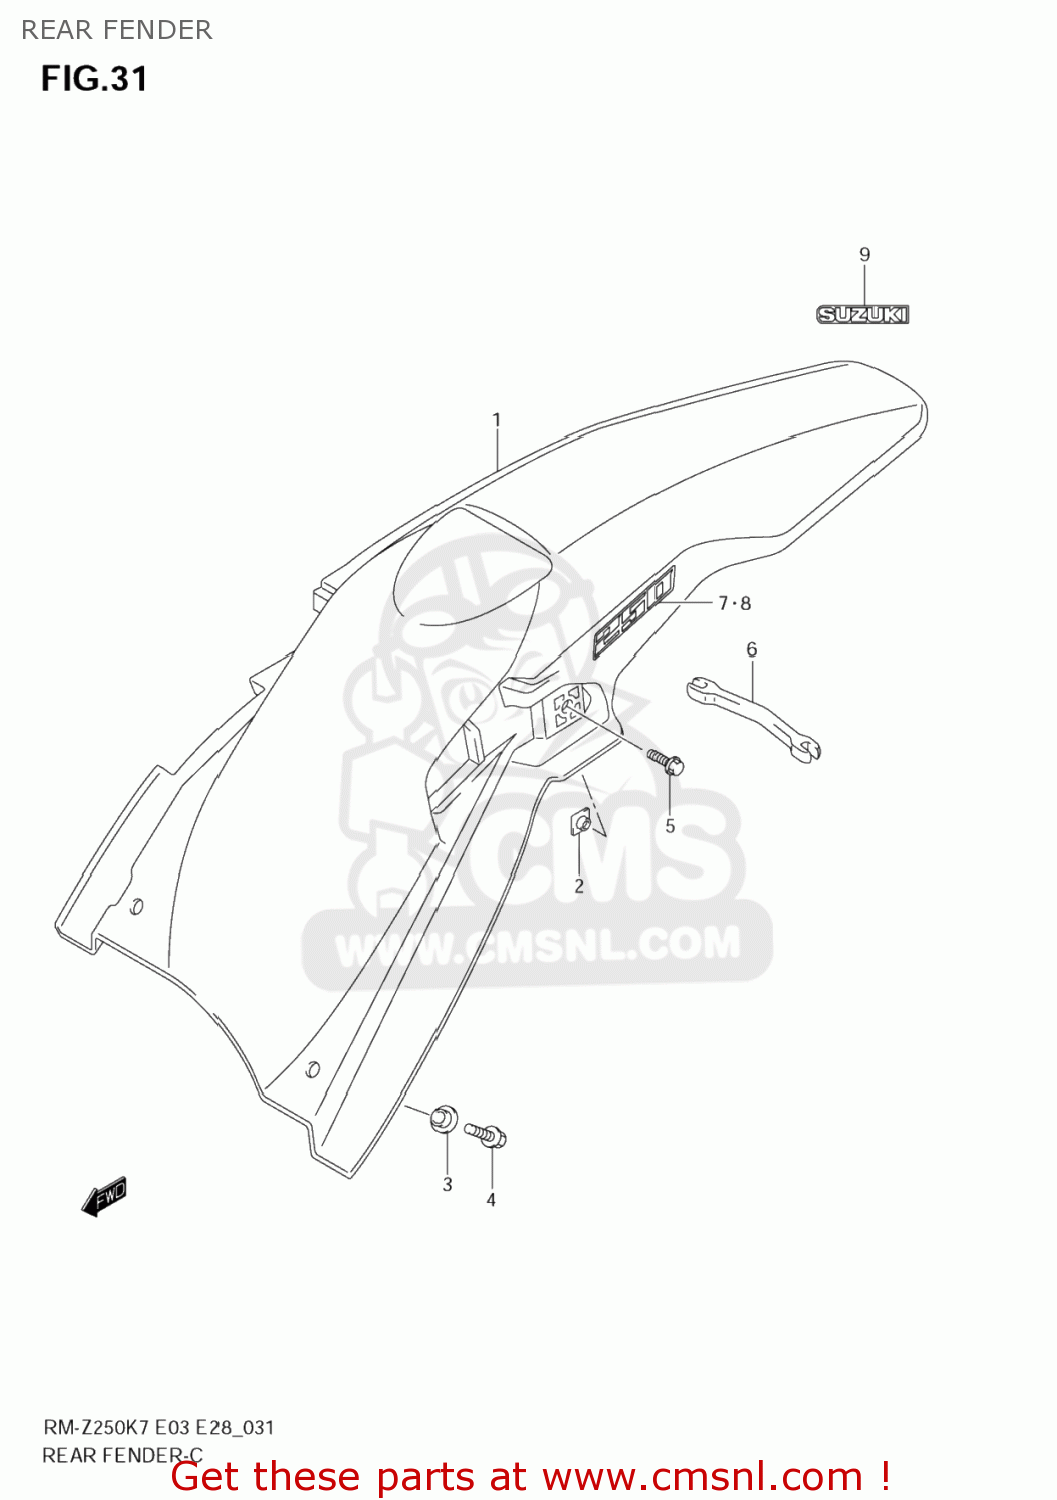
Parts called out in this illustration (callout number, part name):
1	FENDER,RR
2	NUT
3	WASHER
4	BOLT,6X20
5	BOLT(6X16)
6	OPEN SPANNER(6.4X6.8)
7	TAPE,RR FENDER,R
8	TAPE,RR FENDER,L
9	EMBLEM,RR
